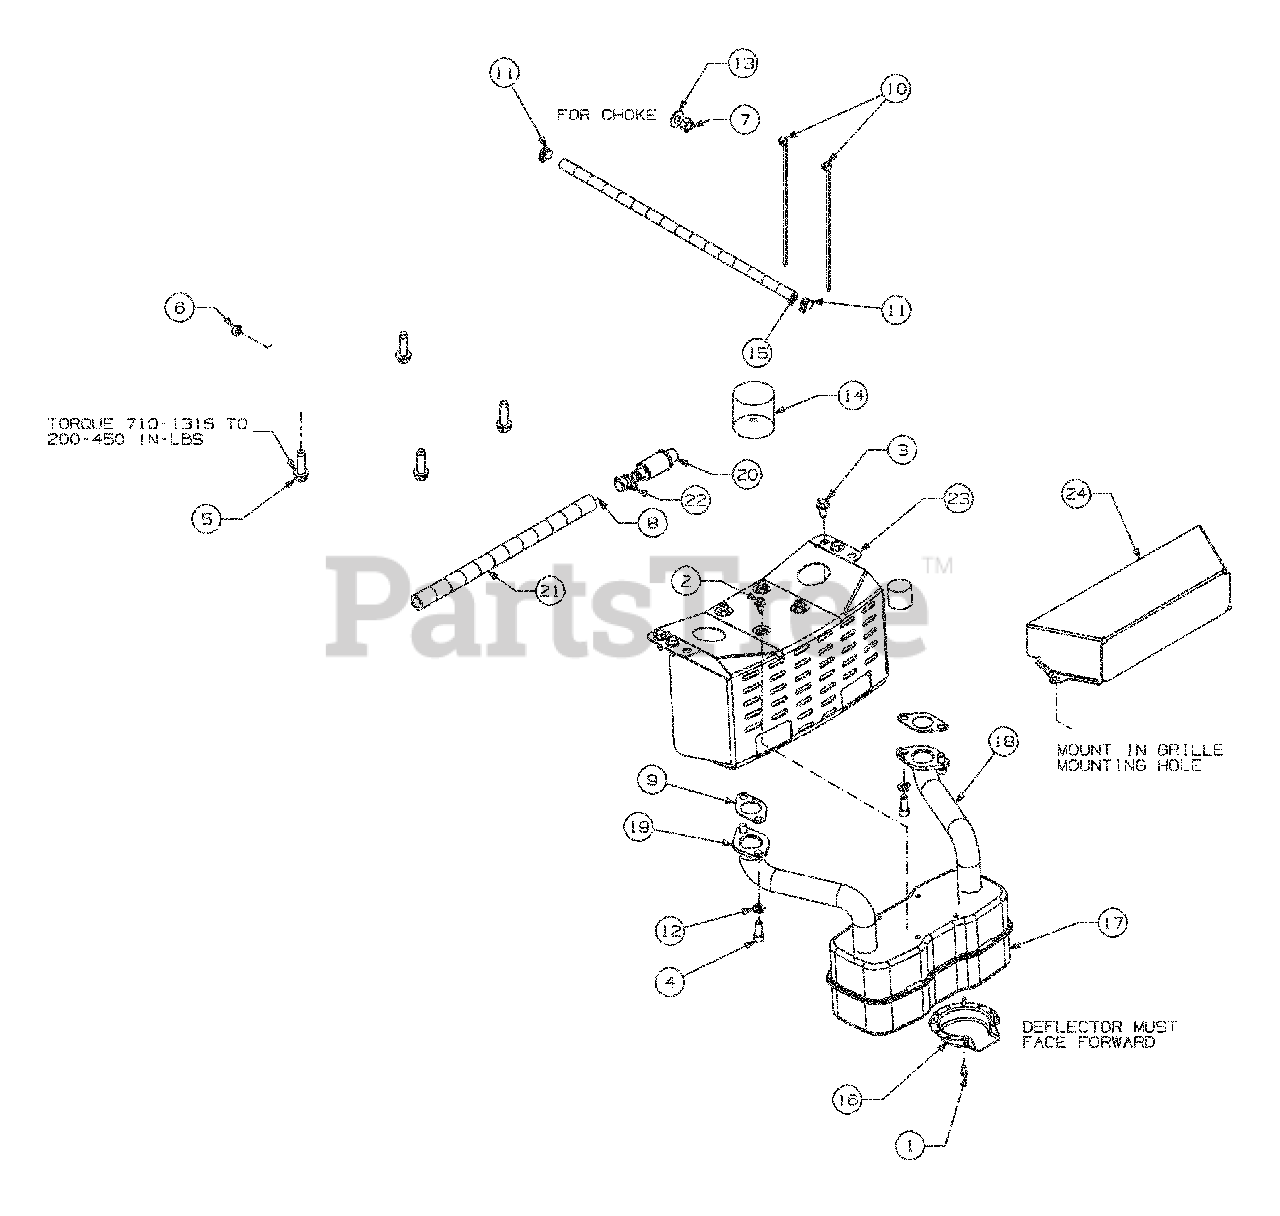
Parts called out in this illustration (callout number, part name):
1	SCR:AB:#8-18:0.500:HXINDWSH
2	SCR:TT:1/4-20:0.500:HXINDWSH
3	SCR:AB:5/16-12:0.750:HXINDWSH
4	SCR:SOC HD:5/16-18:.750
5	SCR:TT:3/8-16:1.250:HXINDWSH:S
6	NUT:HEX:1/4-20:SEMS
7	NUT:HEX:3/8-16:GR8
8	SEALANT:PIPE:PST 567 LOCTITE
9	GSKT:EXH:INTEK TWIN
10	CBL:TIE:3/16 X .05 X 7.4
11	CLAMP:HOSE:.490 DIA.
12	WASH:LOCK:5/16:REGULAR DUTY
13	WASH:FLAT:.406 X .875 X .059
14	OIL:10W30
15	HOSE:FUEL LINE
16	DFL:MFLR:
17	MFLR:DUAL INLET
18	PIPE:EXH:LH TECUMSEH TWIN
19	PIPE:EXH:RH TECUMSEH TWIN
20	DRAIN:OIL
21	HOSE:EXTEN:OIL
22	CAP:DRAIN:OIL
24	SHLD:HEAT:SINGLE
